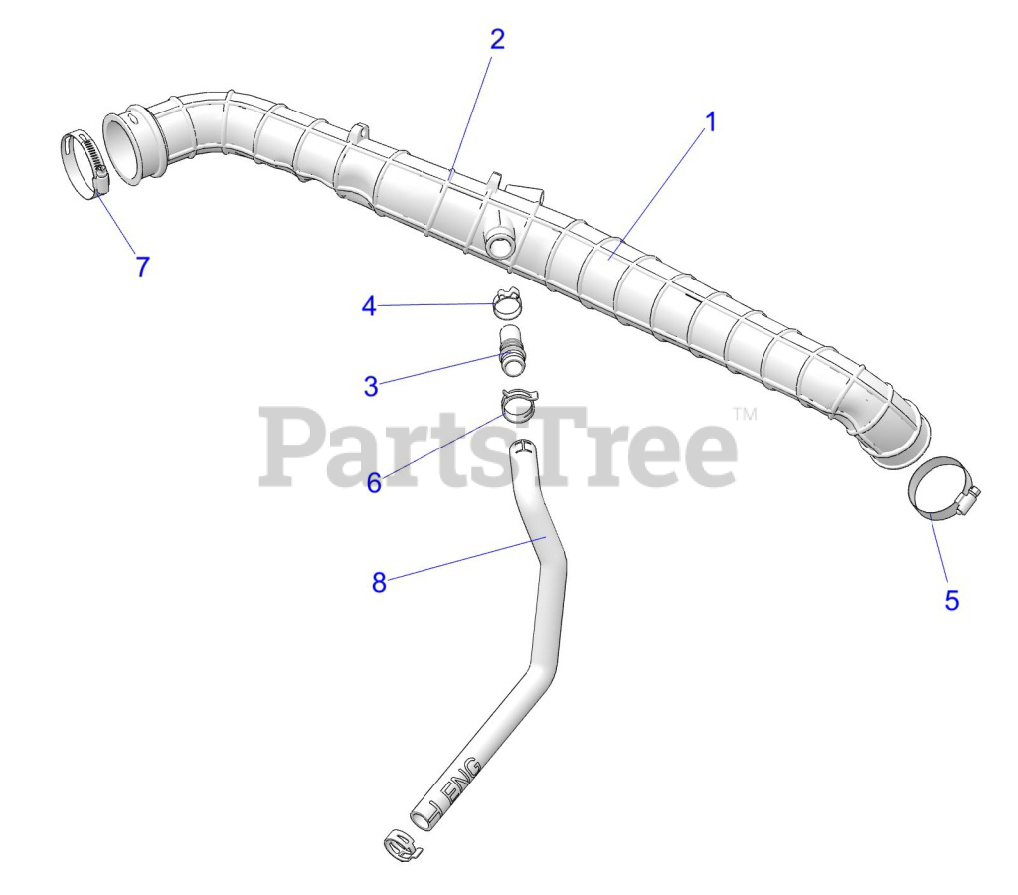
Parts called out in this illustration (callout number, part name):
1	ASM-INTAKE-POST-FILTER
2	HOSE-INTAKE-POST-FILTER
3	FITTING-3/4 DOUBLE BARB
4	CLAMP-HOSE
5	CLAMP- HOSE- S.S.(10)
6	SPRINGBAND-CLAMP 27/12- GREEN
7	CLAMP-HOSE SLOTTED- 60-80 DIA
8	HOSE-VENT-ENGINE
